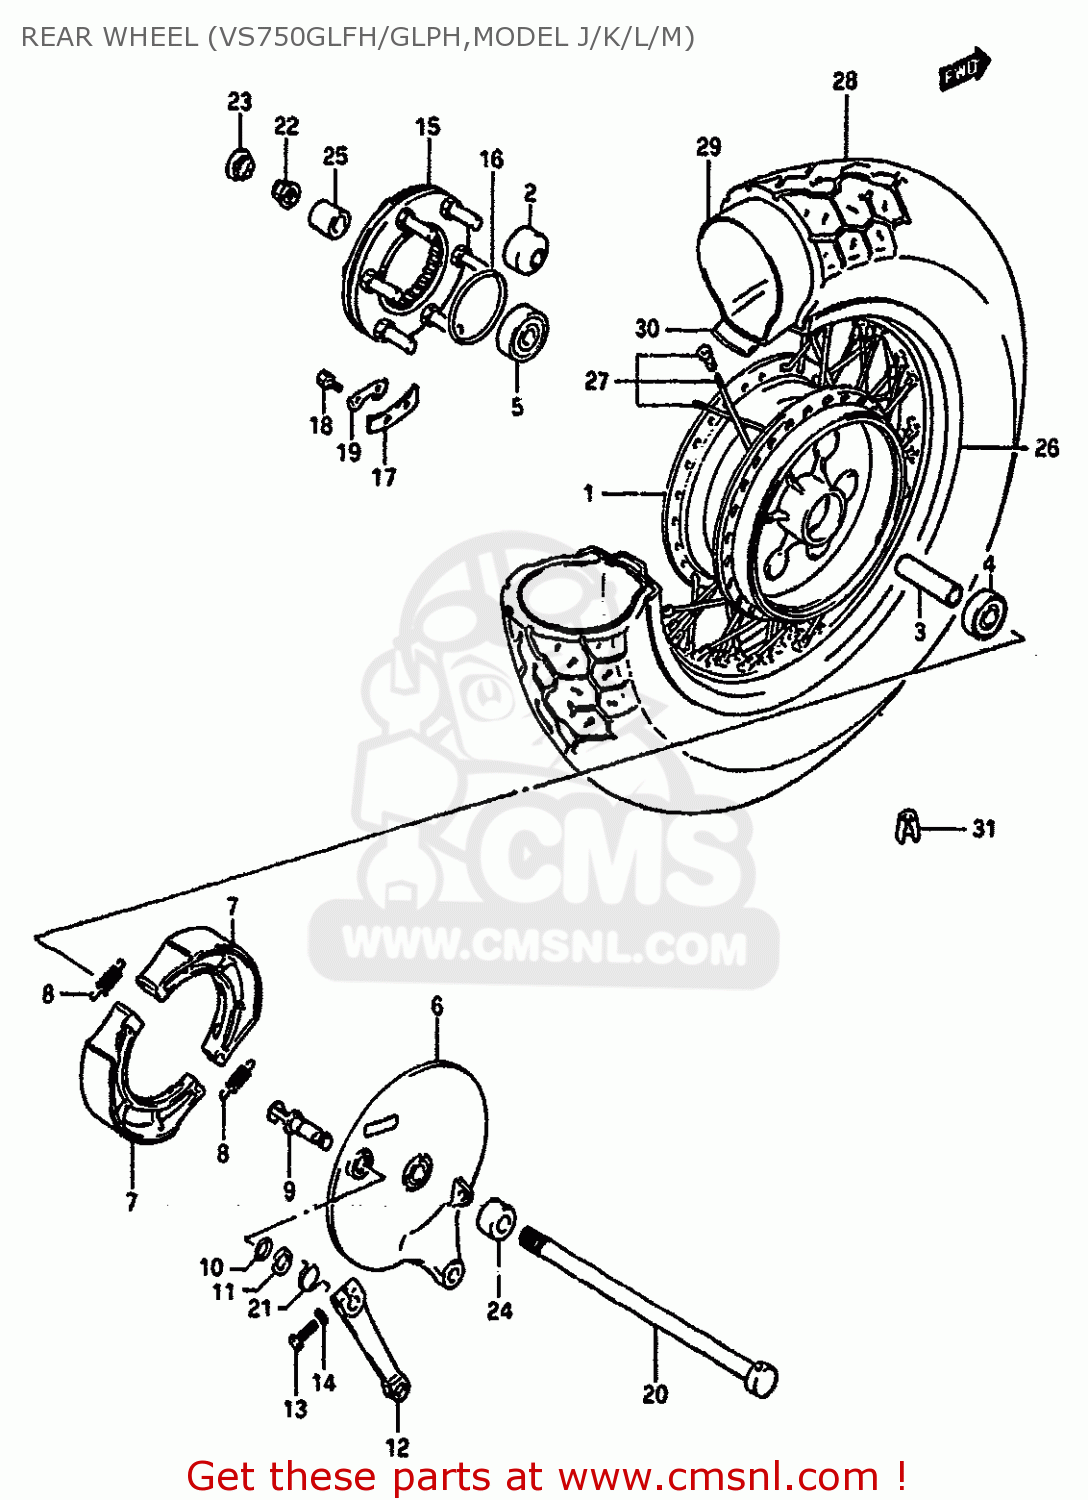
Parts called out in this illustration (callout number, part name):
1	HUB SET,REAR
2	BUSH
3	SPACER(17.5X25X80)
4	BEARING
5	BEARING
6	PANEL,REAR BRAKE ANCHOR
7	SHOE,BRAKE
8	SPRING,BRAKE SHOE
9	CAM,RR BRAKE
10	O-RING,BOSS
11	WASHER (15X24X1.6)
12	LEVER,RR BRAKE CAM
13	BOLT
14	WASHER,LOCK
15	JOINT ASSEMBLY,REAR HUB DRUM
16	O RING(D:2.1,ID:65)
17	WASHER,THRUST(T:1.6)
18	BOLT(6X16)
19	WASHER
20	AXLE,REAR
21	SPRING
22	NUT
23	CAP,RR AXLE,R
24	SPACER,REAR AXLE,RIGHT
25	SPACER,RR AXLE,L
26	RIM,REAR WHEEL
27	SPOKE SET,RR WHEEL
28	TIRE
29	TUBE ASSEMBLY,WHEEL,INNER
30	PROTECTOR,WHL INR TUBE
31	BALANCER,WHEEL
